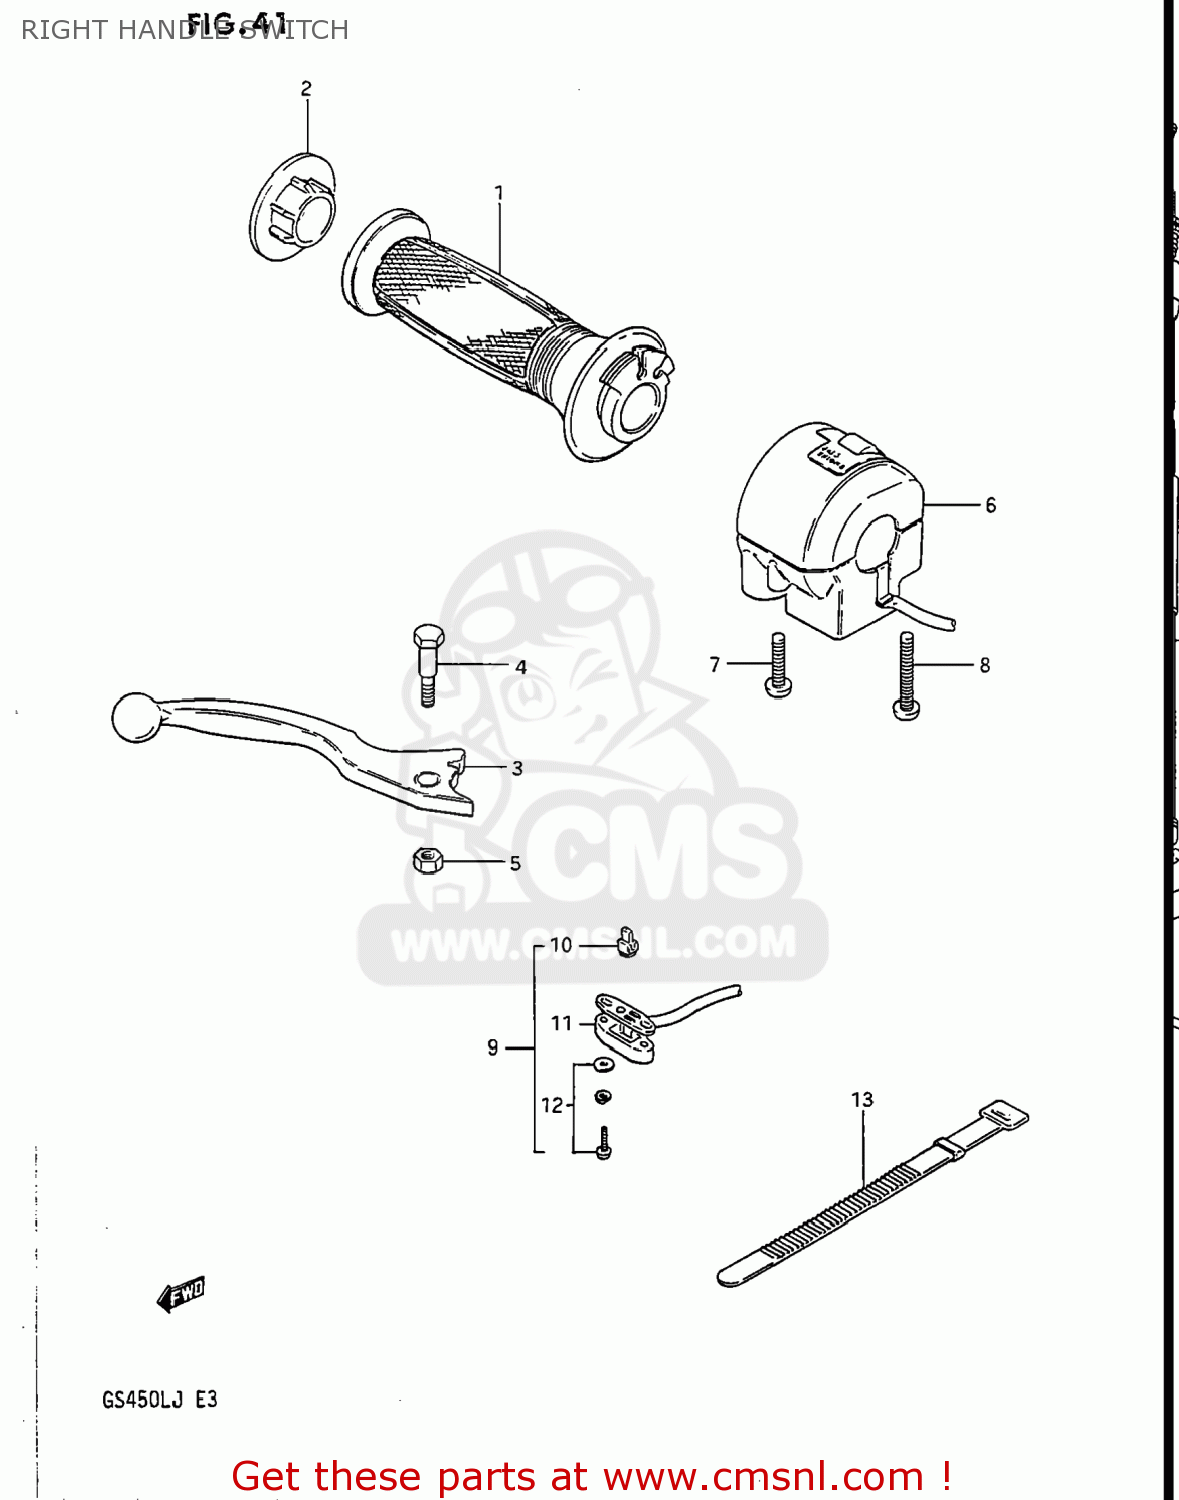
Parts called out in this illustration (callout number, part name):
1	GRIP,THROTTLE
2	CAP,GRIP END
3	LEVER,BRAKE
4	BOLT,LEVER PIVOT
5	NUT
6	SWITCH ASSEMBLY,HANDLE,RIGHT
7	SCREW(5X25)
8	SCREW
9	SWITCH ASSEMBLY
10	CONTACT,SWITCH
11	COVER,FR BK TERMINAL BASE
12	SCREW
13	CLAMP(L:120)
